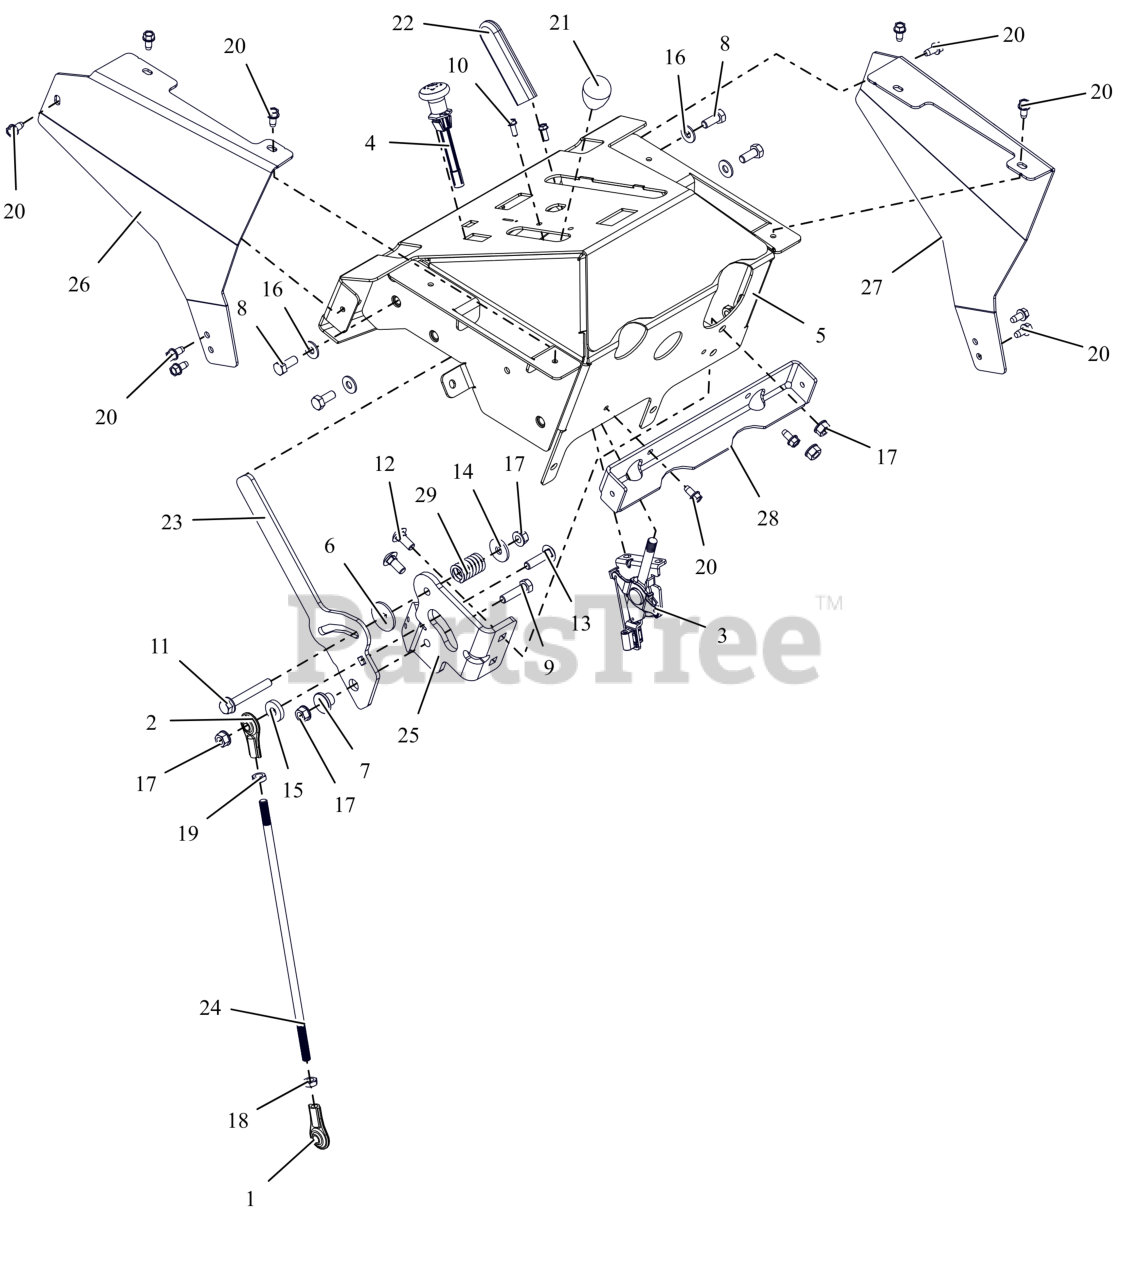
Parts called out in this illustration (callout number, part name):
1	ALIGNABALL, 5/16 RH THREAD
2	ALIGNABALL, 5/16 LH THREAD
3	CABLE, THROTTLE CONTROL 48.00"
4	CABLE, CHOKE (SNAP IN)
5	WLDMT, DASH PANEL (RED)
6	FRICTION WASHER
7	BSHG-FLG .325X.500X.513X.875
8	BLT,HEX .31-18X.75 G5 ZCC
9	BLT, HEX .31-18X1.25 G5 ZCC
10	BLT, HWH #10-24X.50 ZCC
11	BLT,HEX-FLG .31-18X2.25 G5 ZCC
12	BLT,RHSN .31-18X.75 G5 ZCC
13	BTL,RHSSN .313-18 X 1.25 G5 ZCC
14	WSHR,FLT .328X1.00X.094 ZCC
15	WSHR, FLT .328X.870X.179 ZCC
16	WSHR, FLT .312X.734X.065 ZCC
17	NUT,LK-CTR-FLG .31-18 GF ZCC
18	NUT-JAM .312-24 ZCC
19	NUT, JAM-LH .312-24 ZCC
20	SCR-TAP .25-20X.50 HWH ZCC
21	KNOB-CONTROL-BLACK .38-16X.50
22	GRIP,HANDLE
23	LEVER, CRUISE CONTROL (BLACK)
24	ROD, SPEED CONTROL
25	BRKT, SPEED CONTROL PIVOT (BLACK)
26	COVER, RH SIDE (BLACK)
27	COVER, LH SIDE (BLACK)
28	STIFFENER, DASHBOARD (BLACK)
29	SG-COMP .125X.781X1.250
